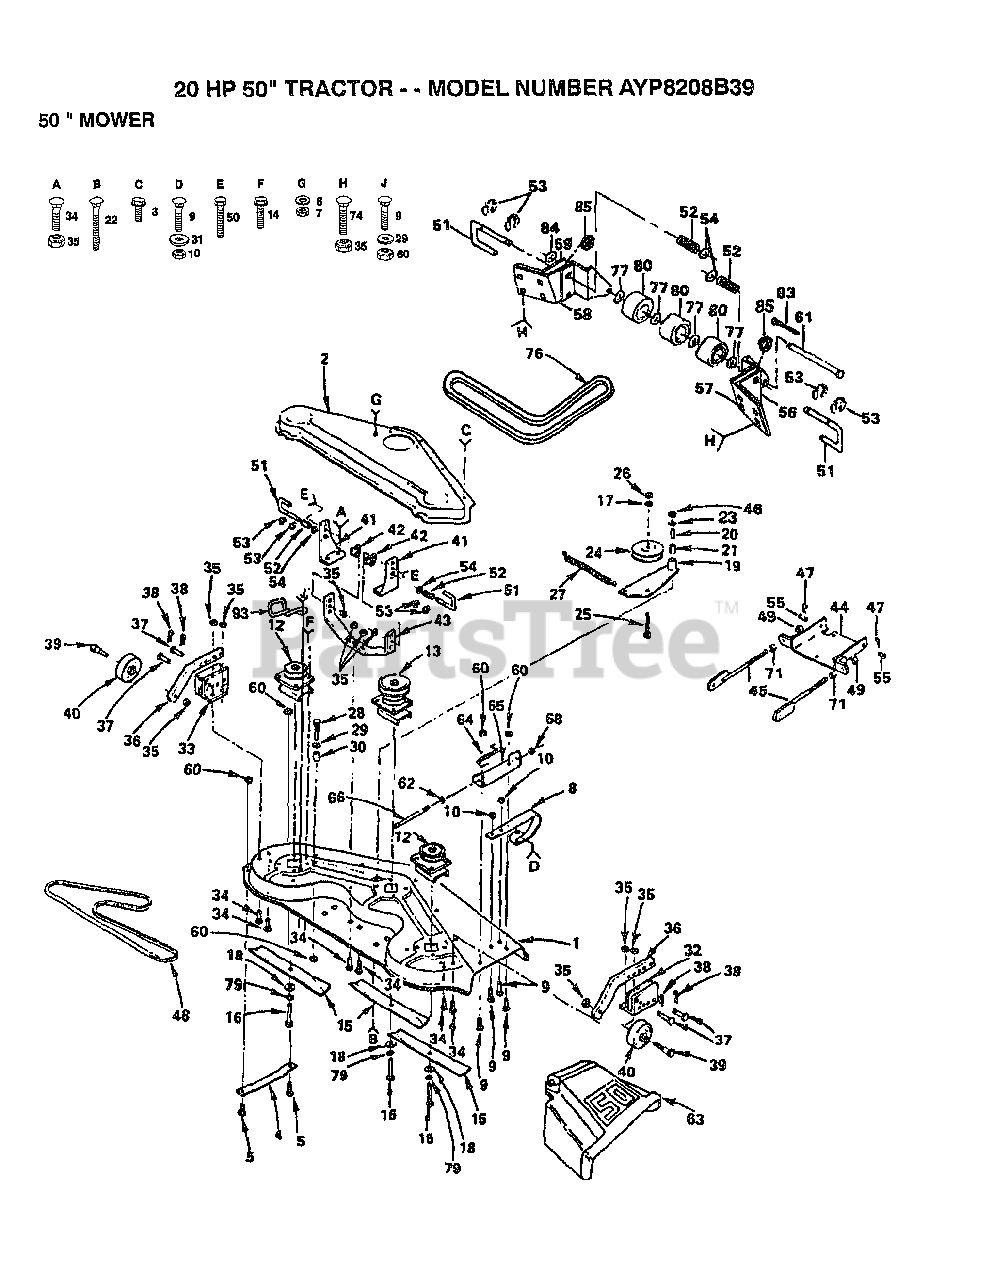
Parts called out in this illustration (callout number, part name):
2	CVR DRIVE DECK
3	SCREW LT
4	RUNNER-LH M
5	BOLT
6	LOCKWASHER
7	NUT.HEX.5/16-18
9	BOLT
13	JACKSHAFT
14	SCREW
15	"BLADE.50""STD.LIFT"
16	BOLT.3/8-24X1-1/2
17	LOCKWASHER
18	WASHER
19	ARM ASSY GT
22	BOLT
24	IDLER-FLAT T
26	NUT.HEX.3/8-16UNC
27	SPRING T
28	BOLT
29	WASHER M
30	SPACER SPLIT LT
31	WASHER
32	GUAGE WHL BRKT GT
33	GUAGE WHL BRKT GT
34	BOLT
36	GUAGE WHL BAR GT
39	BOLT.SHOULDER
40	WHEEL GAGE DONUT
41	SUSP BRKT GT
42	SPACER GT
43	SUSP BRACE GT
45	BRACKET.SUSPEN.AS
46	JAM NUT TI
47	RETAINER.SPRING
48	V-BELT M
49	NUT LTV
50	BOLT
51	RELEASE PIN GT
52	SPRING M
53	KLIP RING
55	CLEVIS PIN GT
56	BRACKET T
57	BRACKET T
58	BRACKET T
59	BRACKET T
61	PIVOT PIN T
62	WASHER
63	DEFLECTOR
64	SPRING TORSION
65	BRKT DEFLECTOR
66	ROD-HINGE T
71	NUT
74	BOLT
76	BELT-V.93.5.MWR
77	WASHER T
80	ROLLER T
83	COTTER PIN
85	SPACER T
93	BELT RETIANER
